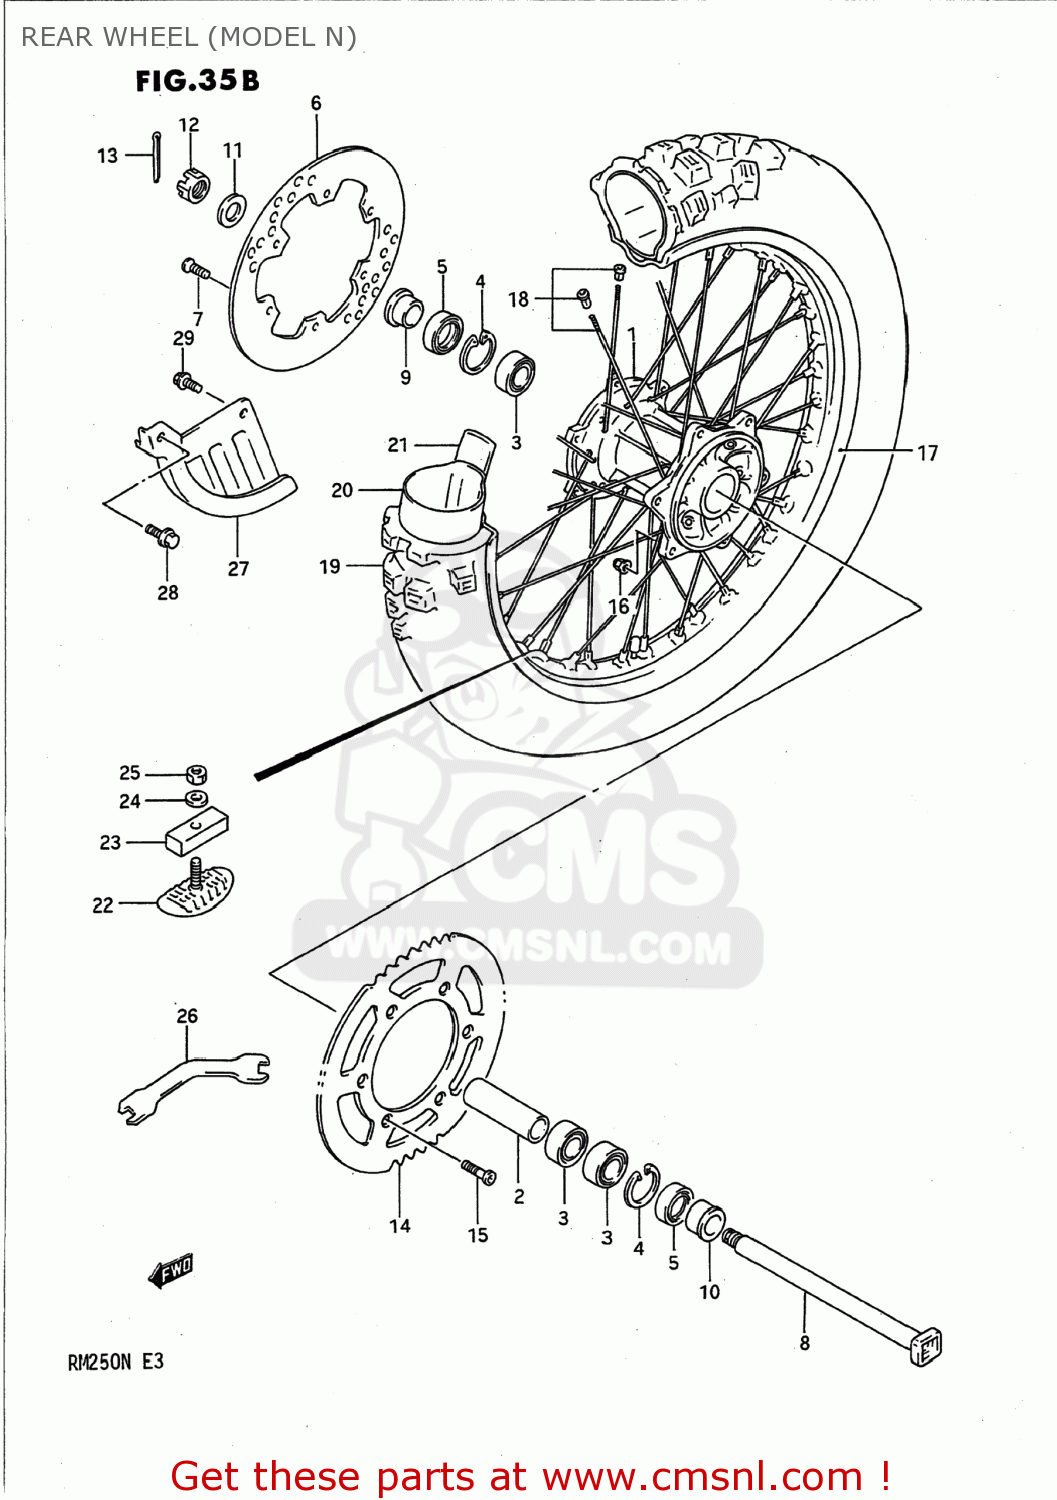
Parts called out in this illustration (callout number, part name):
1	HUB,RR WHEEL
2	SPACER,RR HUB BEARING
3	BEARING
4	CIRCLIP
5	SEAL,OIL(26X42X8)
6	DISC,RR BRAKE
7	SCREW
8	AXLE,REAR
9	SPACER,RR AXLE,R
10	SPACER,REAR AXLE,LEFT
11	WASHER
12	NUT 18MM
13	PIN,COTTER
14	SPROCKET,REAR
15	BOLT(8X30.5)
16	NUT
17	RIM,RR WHEEL(2.15X19 AL)
18	SPOKE SET,RR WHEEL
19	TIRE
20	TUBE ASSY,WHEEL INNER
21	PROTECTOR,WHL INR TUBE
22	STOPPER,BEAD
23	CUSHION,BEAD STOPPER
24	WASHER
25	NUT
26	SPANNER,OPEN
27	COVER,REAR DISC
28	BOLT 6X20
29	BOLT
